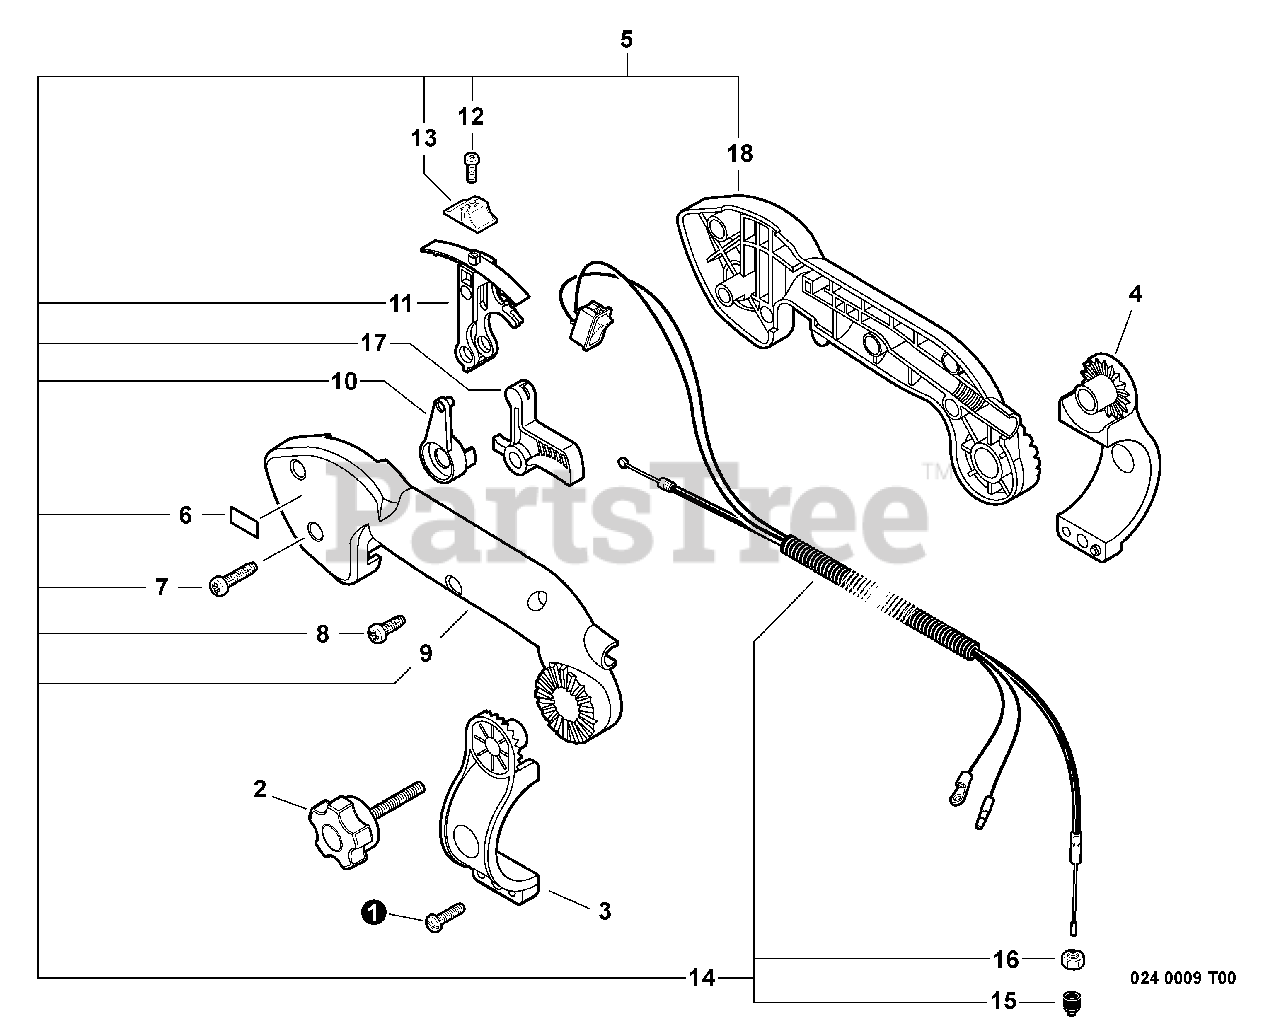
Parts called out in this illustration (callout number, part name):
1	BOLT, TORX 5×20
2	KNOB, SCREW
3	BRACKET, LEFT
4	BRACKET, RIGHT
5	THROTTLE CONTROL KIT - TUBE MOUNT
6	LABEL, CAUTION - IDLE
7	BOLT, TORX 5×25
8	BOLT, TORX 5×20
9	CONTROL HANDLE - LEFT
10	LEVER, THROTTLE
11	CONTROL, THROTTLE
12	SCREW 3×14
13	KNOB, CONTROL
14	CABLE ASSY, CONTROL
15	CAP, DUST
16	NUT, HEX M6
17	TRIGGER, THROTTLE
18	CONTROL HANDLE - RIGHT
